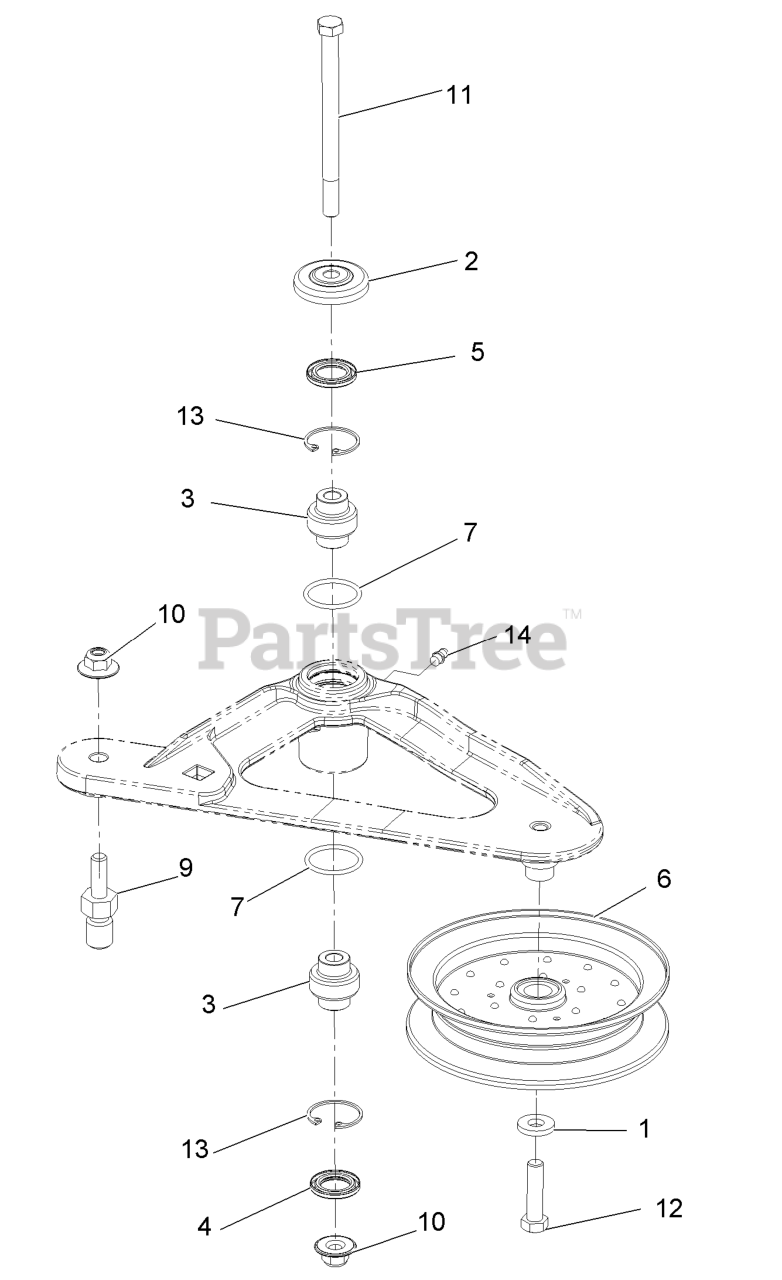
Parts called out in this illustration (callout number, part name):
2	GUARD-TOP
3	BEARING-SPHERICAL
4	SEAL-LIP, DOUBLE
5	SEAL-LIP, SINGLE
10	Nut-Nyloc 3/8-16 Flg
11	SCREW-SHOULDER, HH
12	SCREW-HH
13	RING-SNAP
14	FITTING-GREASE
